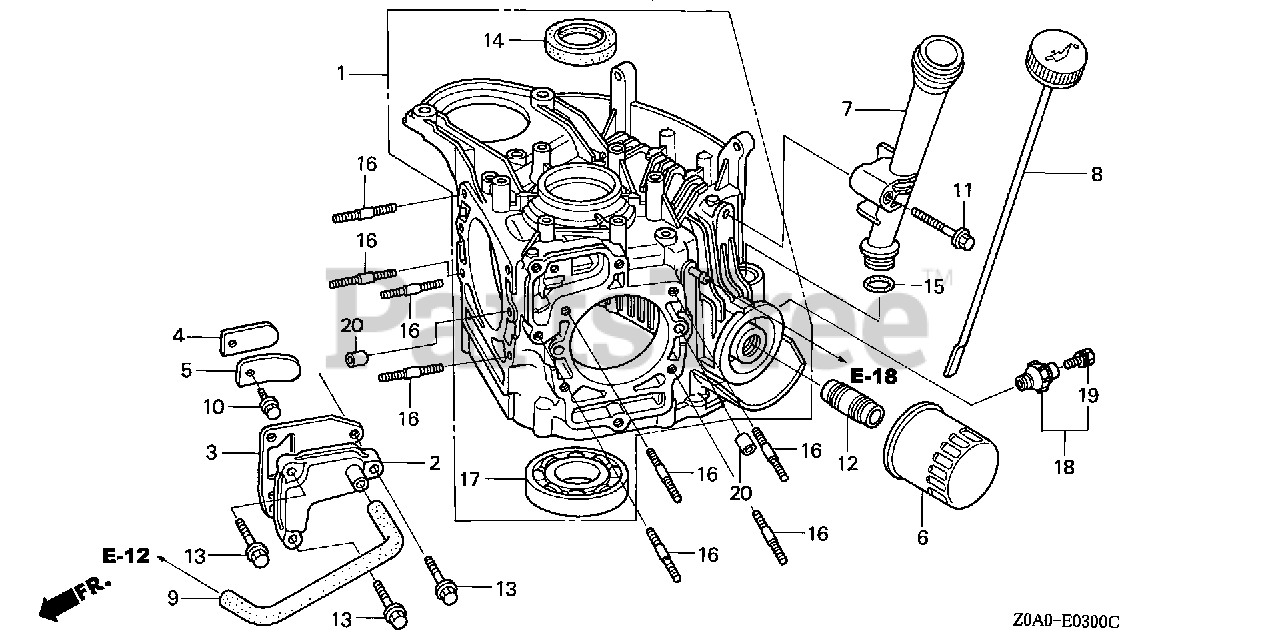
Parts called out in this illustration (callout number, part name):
1	CRANKCASE ASSY. (810)
2	COVER, BREATHER
3	GASKET, BREATHER COVER
4	PLATE, VALVE
5	STOPPER, VALVE
6	FILTER, OIL
6	FILTER, OIL (DENSO)
7	EXTENSION, OIL FILLER
8	GAUGE, OIL LEVEL
9	TUBE, BREATHER
10	BOLT, FLANGE (5X10) Use from Engine SN 2327377.
11	BOLT, FLANGE (6X45)
12	HOLDER, OIL FILTER
13	BOLT, FLANGE (6X25) Use up to Engine SN 2056819.
14	OIL SEAL (35X52X8)
15	O-RING (22.5X2.2) Use from Engine SN 1257295.
16	BOLT 2, STUD (8X28)
17	BEARING, RADIAL BALL (6207)
20	PIN A, DOWEL (8X14)
